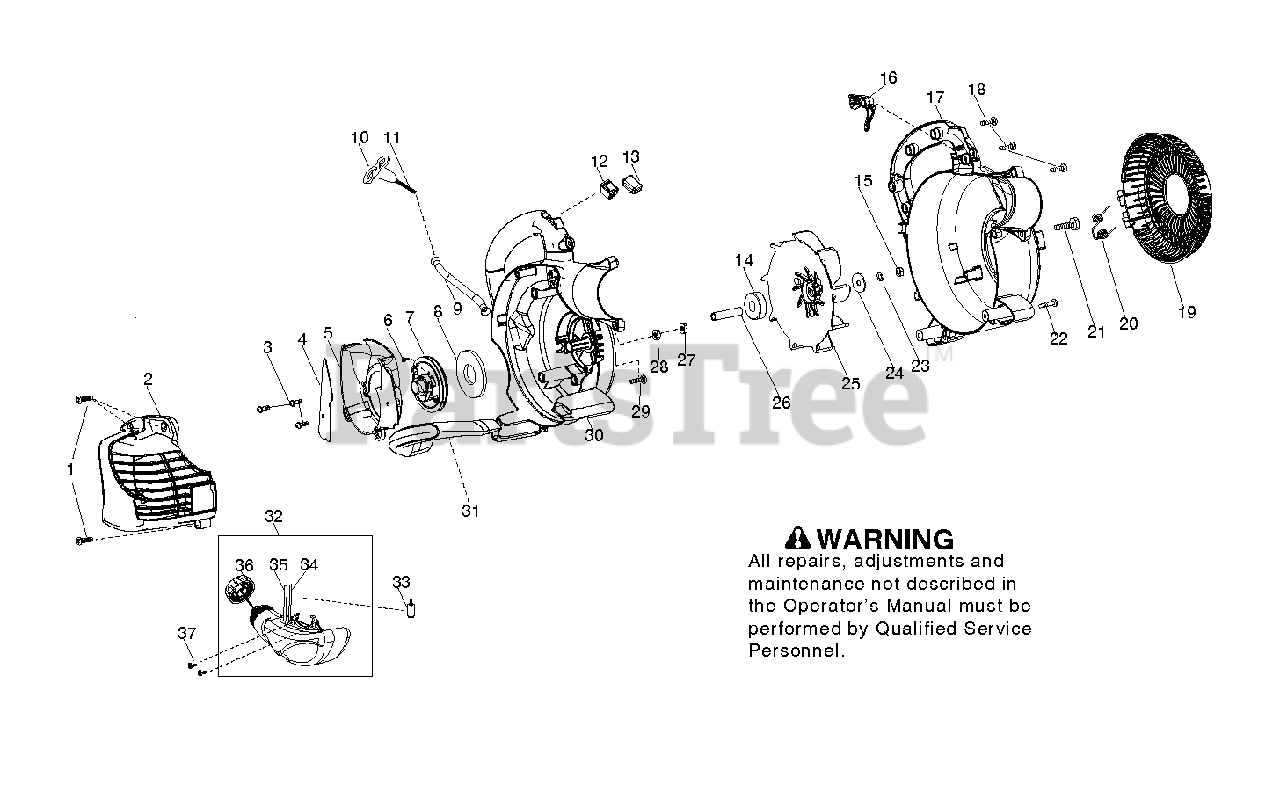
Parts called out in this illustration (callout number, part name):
2	ASSY COVER ENGINE
4	SHIELD BAFFLE
6	SCREW SEMS TOOTHED WASHER
7	KIT STARTER PULLEY
8	SPRING STARTER SA
9	TUBE STARTER ROPE
10	HANDLE STARTER BLK
11	KIT ROPE
12	KIT SWITCH
13	Protector Switch
14	Hub Bearing
16	TRIGGER THROTTLE SRS RED
19	DOOR VAC BLACK
20	SPRING VAC DOOR
21	KNOB BLOWER
22	SCREW #10 PLASTITE 1.362
23	LOCK WASHER
24	Impeller Washer
25	ASSY IMPELLAR HUB
26	FLYWHEEL SPACER
31	HANDLE VAC BLACK
32	ASSY FUEL TANK
33	Pre-Flushed Fuel Pick-up Assembly
34	KIT-LINE
35	LINE KIT
36	FUEL CAP ASSY
37	SCREW FUEL TANK RETAINER
39	DECAL WARNING
40	ASSY VAC BAG GAS W/STRAP
41	TUBE VAC UPPER BLACK
42	TUBE VACUUM J BLACK
43	TUBE LOWER VAC
